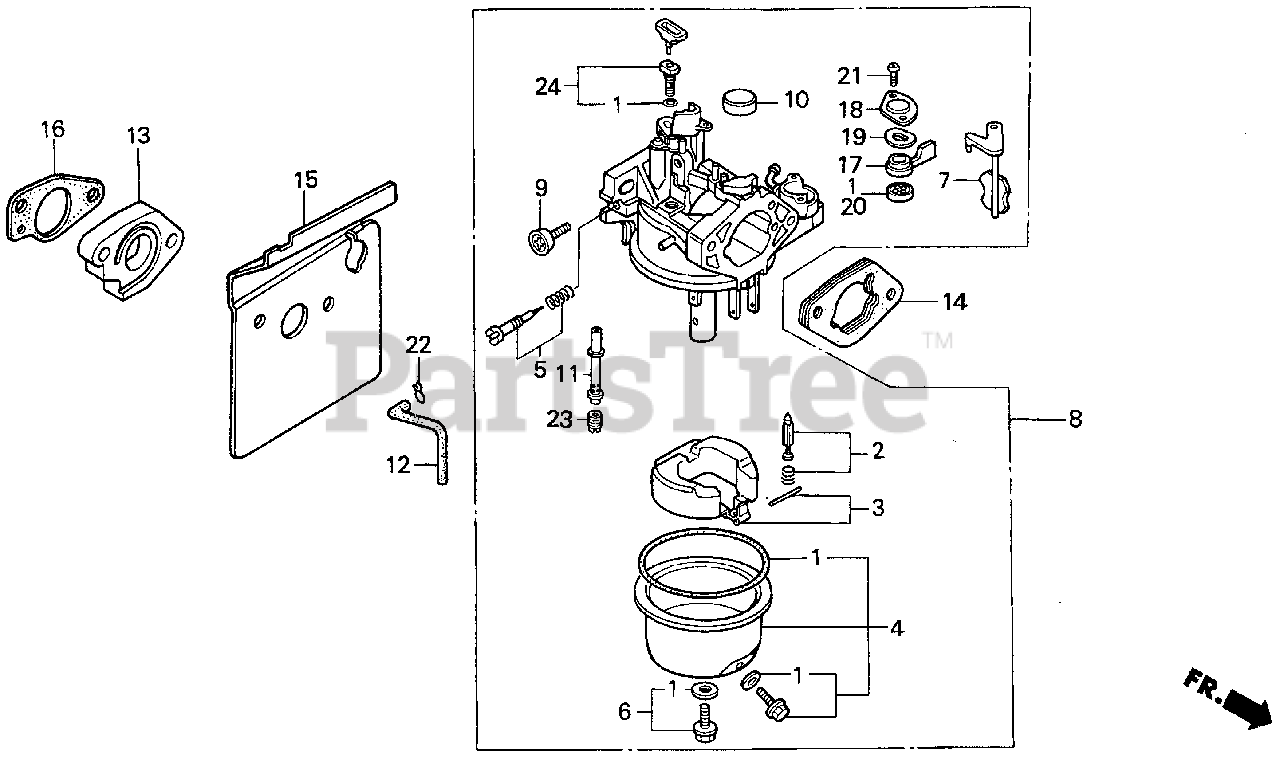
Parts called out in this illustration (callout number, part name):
1	GASKET SET
2	VALVE SET, FLOAT
3	FLOAT SET
4	CHAMBER SET, FLOAT
5	SCREW SET, PILOT
6	SCREW SET B
7	CHOKE SET
8	CARBURETOR ASSY.
9	SCREW, THROTTLE STOP
10	CAP, CHOKE LEVER DUST
11	NOZZLE, MAIN
12	TUBE, AIR VENT (75MM)
13	INSULATOR, CARBURETOR
14	SPACER, CARBURETOR
15	GASKET, CARBURETOR
16	GASKET, INSULATOR
17	LEVER, VALVE
18	PLATE, LEVER SETTING
19	SPRING, VALVE LEVER
20	GASKET, VALVE
21	SCREW, PAN (3X8)
22	CLIP, TUBE (B8)
23	JET, MAIN (#82)
23	JET, MAIN (#85)
23	JET, MAIN (#88)
24	JET SET, PILOT (#40)
